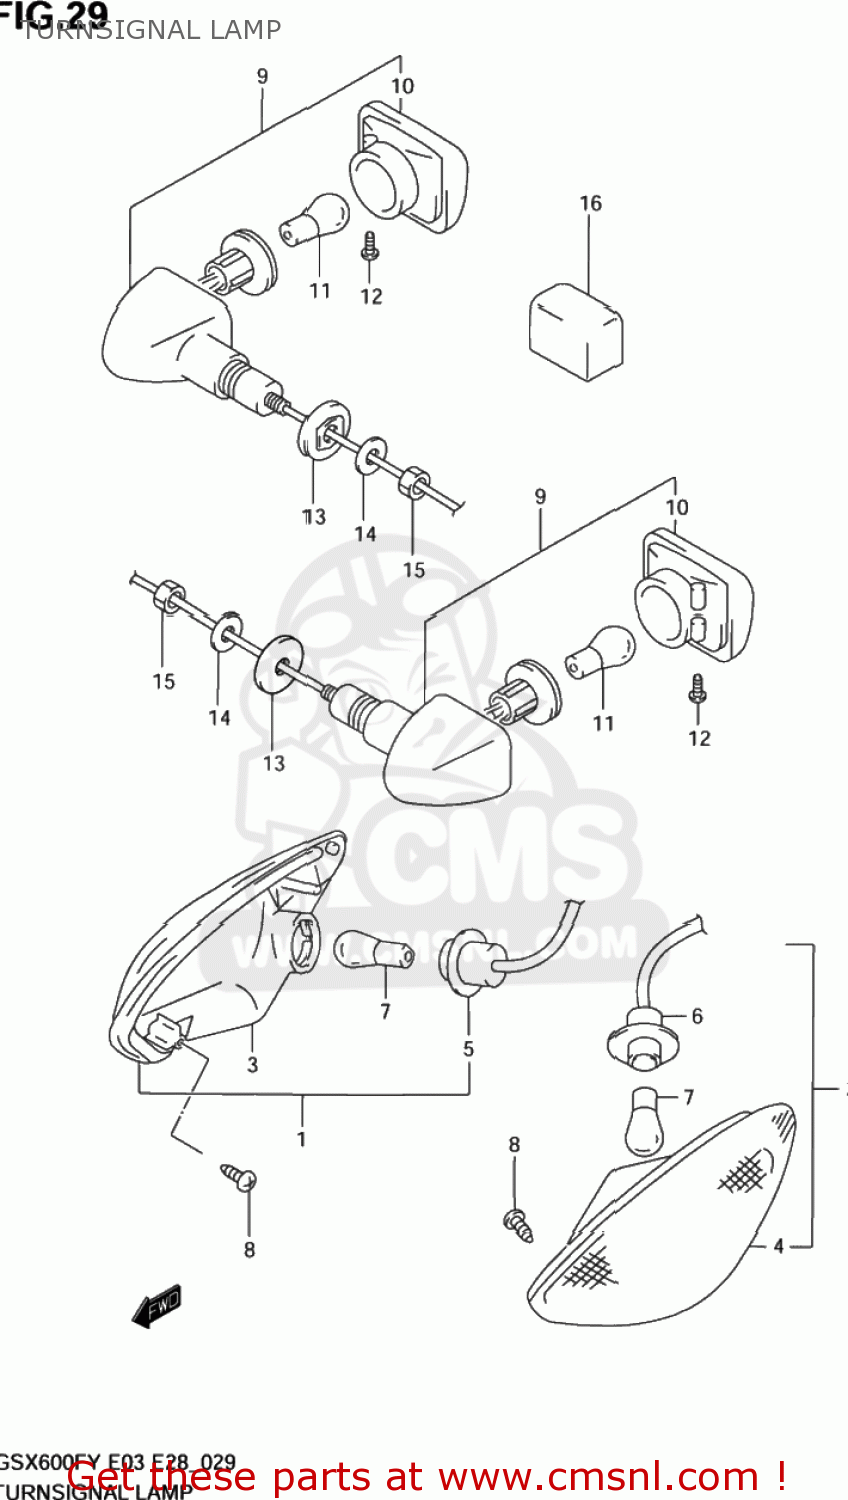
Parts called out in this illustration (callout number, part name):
1	LAMP ASSY,FR TURN SIGNAL,R
2	LAMP ASSY,FR TURN SIGNAL,L
3	LAMP UNIT,R
4	LAMP UNIT,L
5	SOCKET & CORD
6	SOCKET & CORD
7	BULB(12V21W)
8	SCREW
9	LAMP ASSY,RR TURNSIGNAL,R
10	LAMP UNIT
11	BULB(12V21W)
12	SCREW
13	SPACER,RR TURNSIGNAL
14	WASHER(10.5X30X2.3)
15	NUT
16	RELAY ASSY,TURNSIGNAL LAMP
